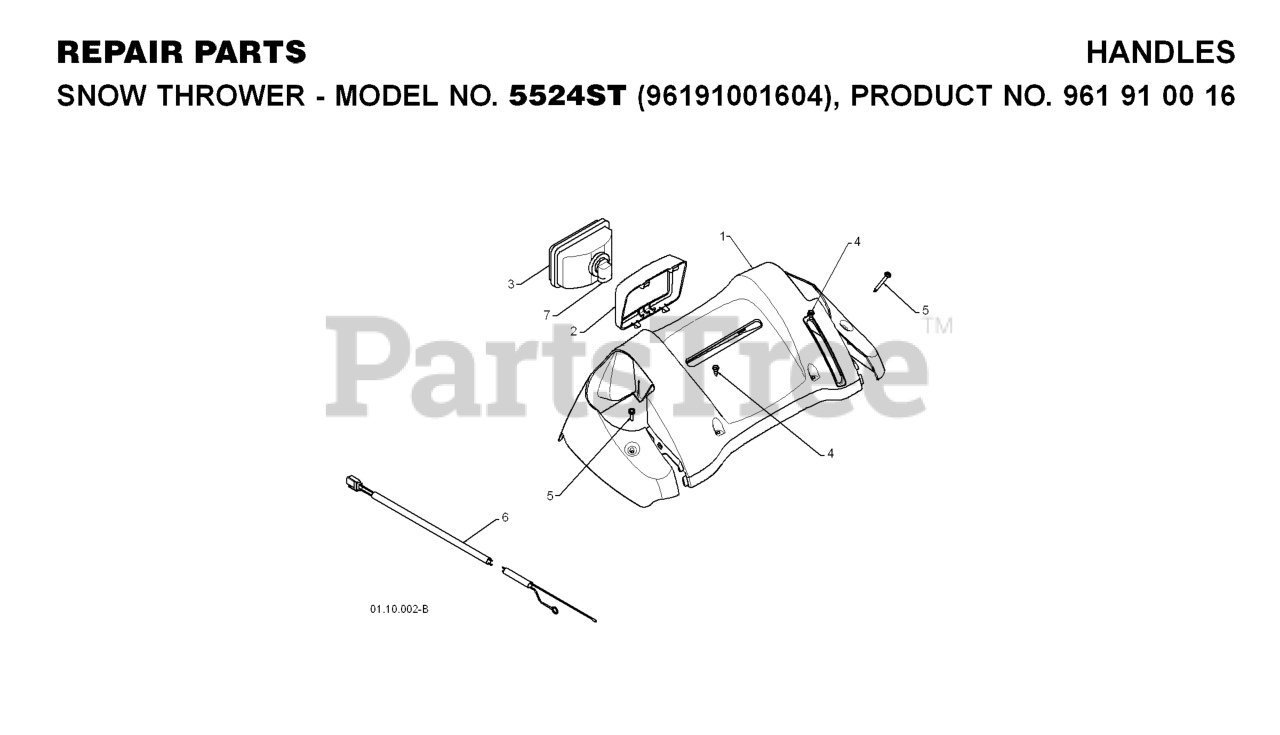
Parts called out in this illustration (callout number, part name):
1	PANEL.CONSOLE.HEADLIGHTS
2	BEZEL.HEADLIGHT.BLACK
3	HEADLIGHT.HALOGEN.SNOW
4	SCREW, HEX HEAD, TAPPING
5	SCREW, HEX HD TAPPING #10-24 1
6	HARNESS.WIRE.HALOGEN
7	BULB.HEADLIGHT.HALOGEN.
